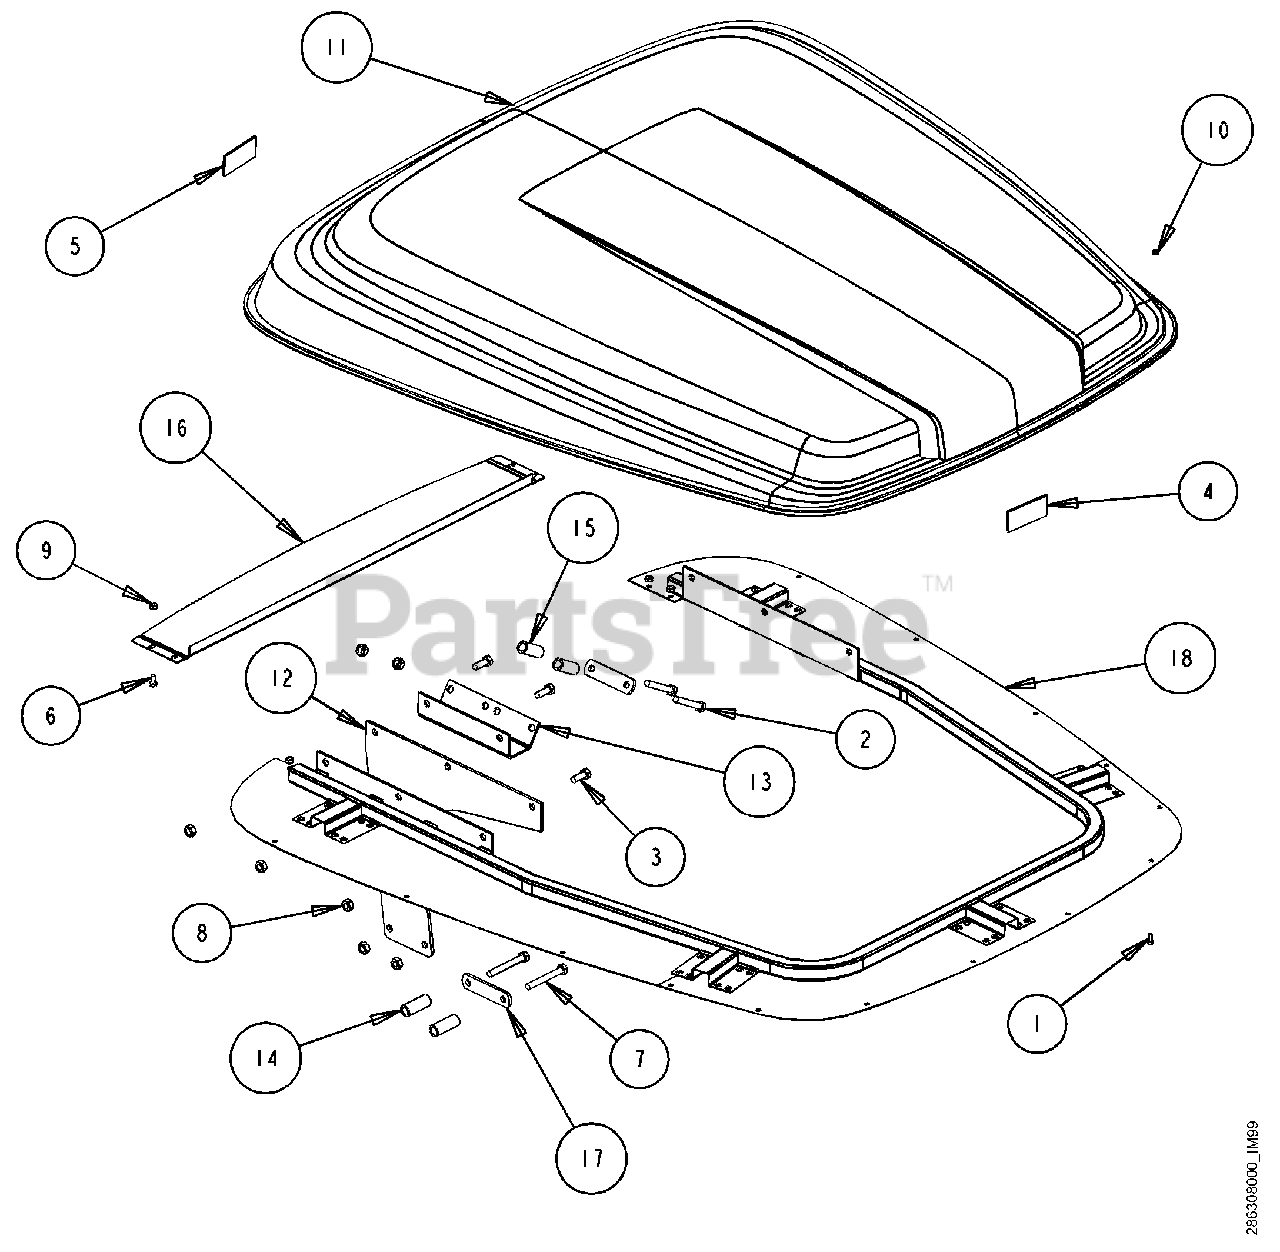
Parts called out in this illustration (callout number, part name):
4	Reflector Amber
5	Reflector Red
11	Canopy, Plastic
12	Mount Plate
13	Top Bracket
14	Bushing (1 3/4" Long)
15	Bushing (1 15/16" Long)
16	Rear Flange
17	Inner Plate
18	Canopy Frame
